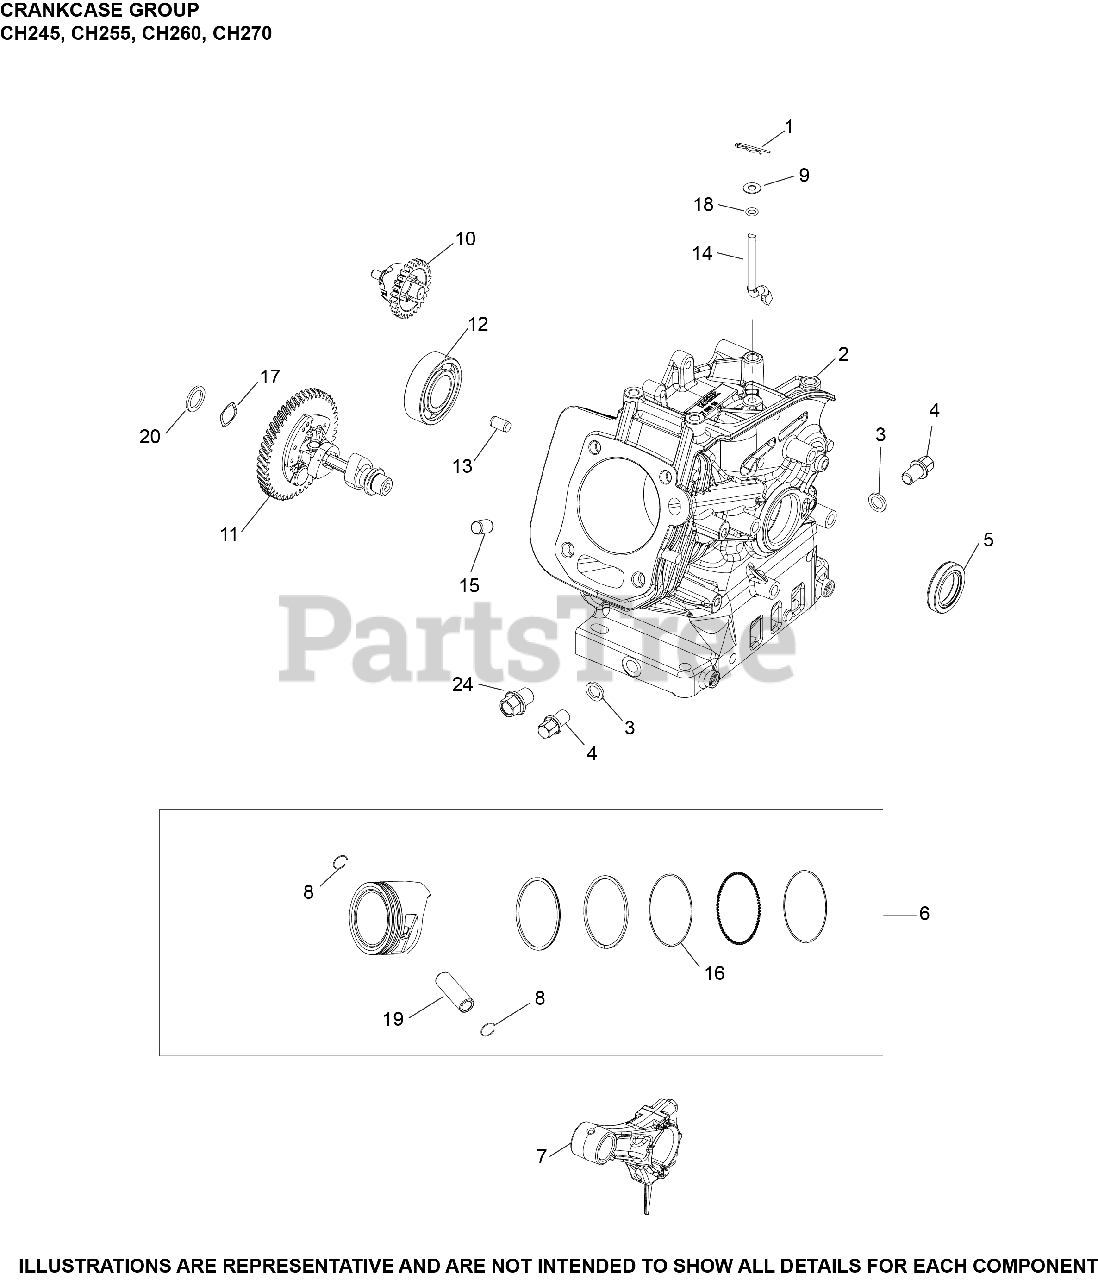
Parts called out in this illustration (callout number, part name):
1	CLIP, GOVERNOR SHAFT
2	CRANKCASE ASSEMBLY
3	WASHER, DRAIN PLUG - (#1846801S)
4	KIT, DRAIN PLUG
5	SEAL, OIL
6	KIT, PISTON USE 17 874 10-S
6	KIT, PISTON (0.25 O.S.)
7	ROD, CONNECTING ASSEMBLY
8	RETAINER, PISTON PIN
9	WASHER, FLAT (13MM OD)
10	GOVERNOR ASSEMBLY
11	CAMSHAFT ASSEMBLY
12	BEARING, BALL
13	PIN, DOWEL
14	SHAFT, GOVERNOR CROSS
15	DOWEL, CYLINDER HEAD-(#1438013S)
16	RING SET, PISTON
16	RING SET
16	RING SET (0.25 O.S.)
19	PIN, PISTON
